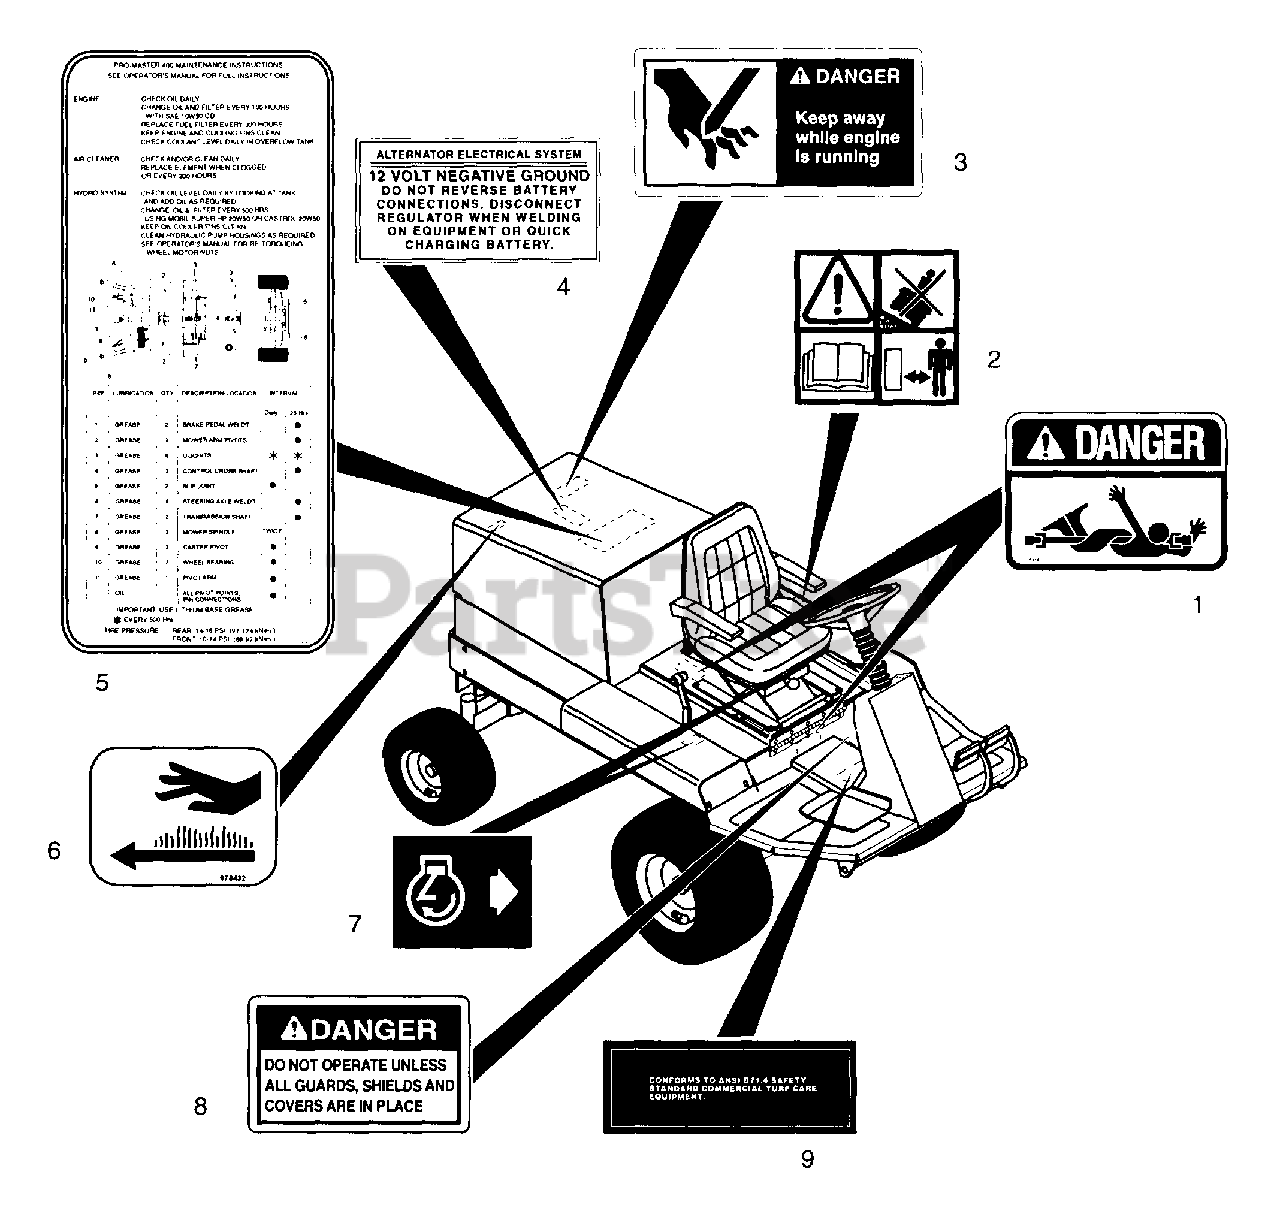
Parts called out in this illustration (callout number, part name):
1	Decal - PTO Danger
2	Decal - International Symbols (989302,303)
3	Decal - Danger Hand
4	Decal - E-System Warning
5	Decal - G-Series Maintenance
6	Decal - Hot Surface
7	Decal - Start
8	Decal, Belt Installation
9	Decal - ANSI
